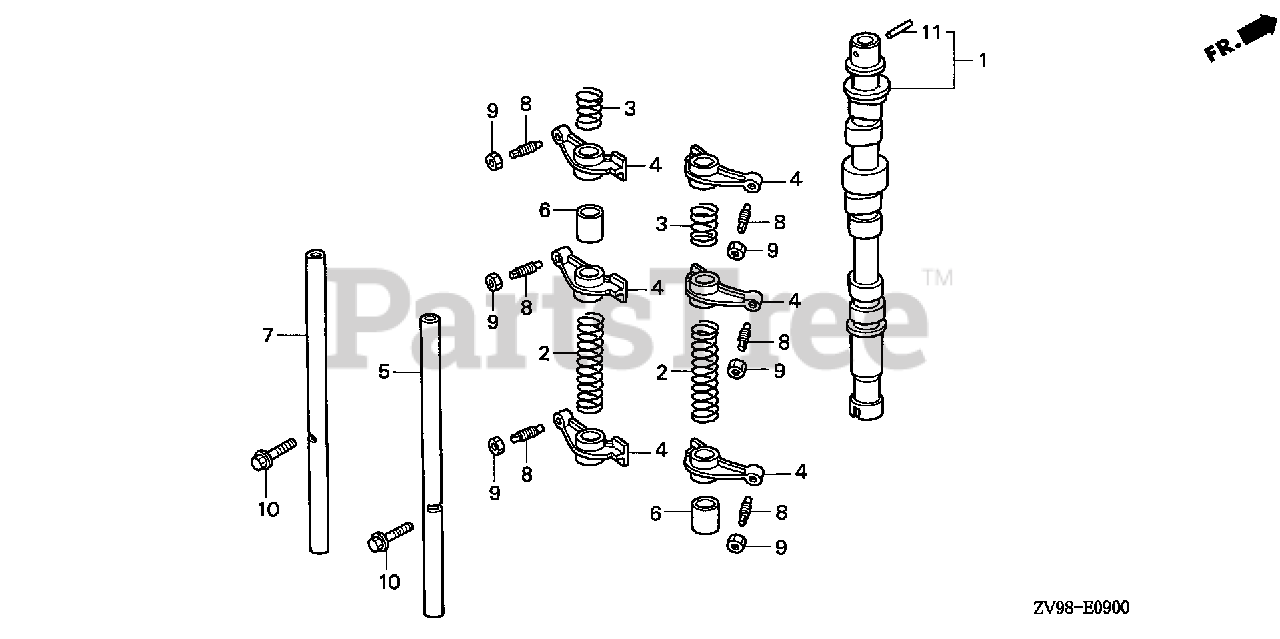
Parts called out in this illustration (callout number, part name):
2	SPRING, ROCKER ARM A
3	SPRING, ROCKER ARM B
4	ARM, VALVE ROCKER
5	SHAFT, IN. ROCKER ARM
6	COLLAR, ROCKER
7	SHAFT, EX. ROCKER ARM
8	SCREW, TAPPET ADJUSTING
9	NUT, TAPPET ADJUSTING
10	BOLT, FLANGE (6X28)
11	ROLLER (3X16.8)
